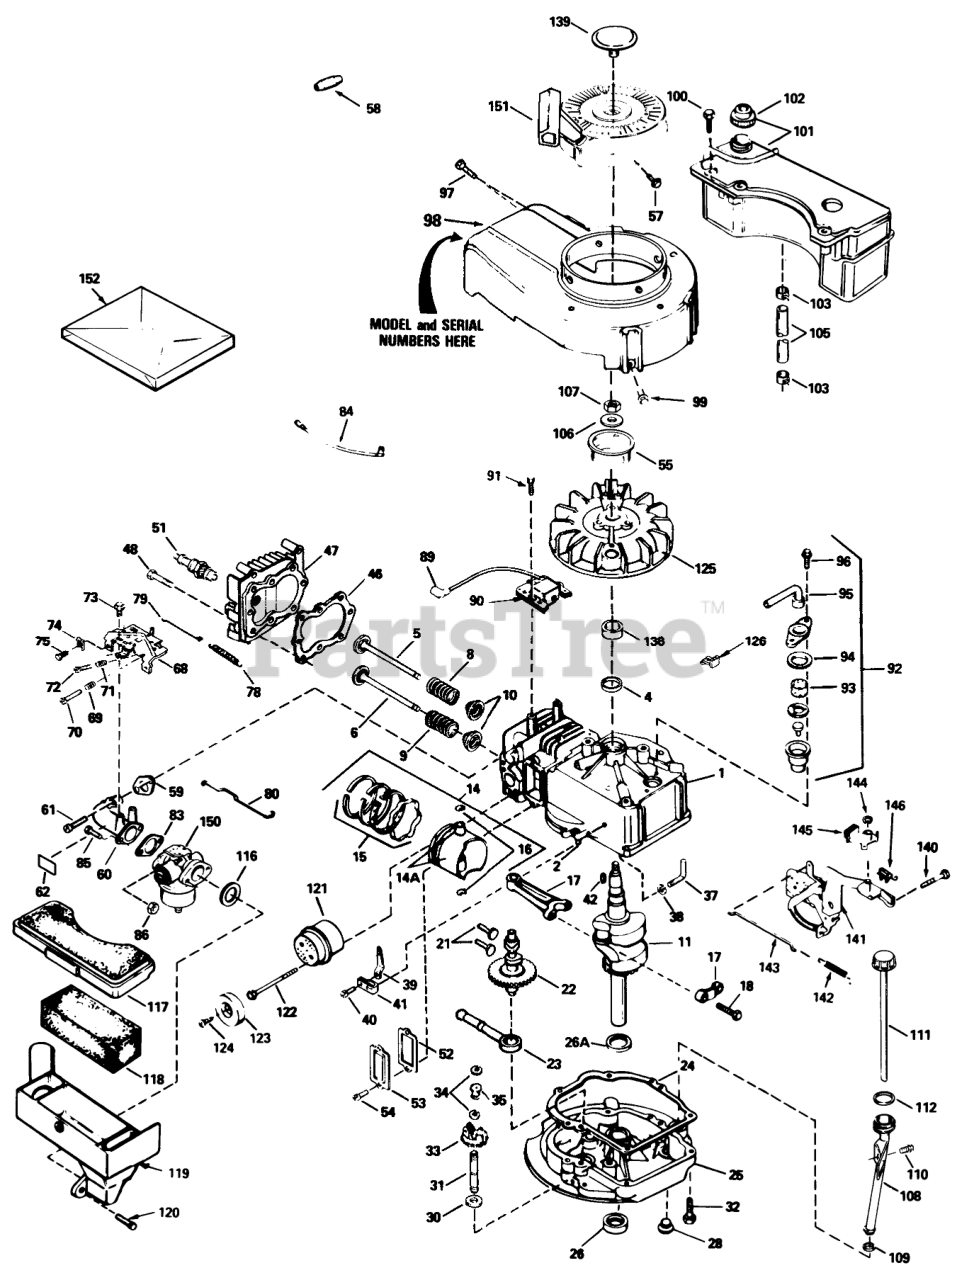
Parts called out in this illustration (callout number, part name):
1	Cylinder Assembly (Incl. Ref. #2 & 4)
2	Pin-Dowel
4	Seal-Oil
5	Valve-Intake (Std.) (Incl. Ref. #10)
5	Valve-Intake (1/32" oversize) (Incl. Ref. #10)
6	Valve-Exhaust (Std.) (Incl. Ref. #10)
6	Valve-Exhaust (1/32" oversize) (Incl. Ref. No.10)
8	Seal Assy., Intake
9	Spring-Valve
10	Cap-Valve, Spring
11	Crankshaft
14	Piston-Pin & Ring Assy. (Std.) (Incl. Ref. #14A, 15 & 16)
14	Piston-Pin & Ring Assembly (.010 oversize) (Incl. Ref. #14A, 15 & 16)
14	Piston-Pin & Ring Assembly (.020 oversize) (Incl. Ref. #14A, 15 & 16)
14A	Piston & Pin Assembly (Std.) (Incl. Ref. #16)
14A	Piston & Pin Assembly (.010 oversize) (Incl. Ref. #16)
14A	Piston & PiN Assembly (.020 oversize) (Incl. Ref. #16)
15	Ring Set-Piston (Std.)
15	Ring Set, Piston(.0100versize)
15	Ring Set (.020" OS)
16	Ring-Retaining, Piston Pin
17	Rod Assembly-Connecting (Incl. Ref. #18)
18	Bolt-Rod, Connecting
21	Lifter-Valve
22	Camshaft(Mech.Comp. Release)
23	Oil Pump ASM
24	Gasket
25	Flange Assembly-Mounting (Incl. Ref. #26, 28 & 31)
26	Seal-Oil
26A	Washer-Thrust
28	Plug Oil Drain
30	Washer-Flat
31	Shaft-Governor
32	Screw (1/4-20 x 1-1/4)
33	Gear Assembly-Governor (Incl. Ref. #30)
34	Ring-Retaining
35	Spool-Governor
37	Rod-Governor (Incl. Ref. #38)
38	Washer-Flat
39	Governor Lever
40	Screw
41	Clamp-Lever, Governor
42	Key-Flywheel
46	63573 GIL 42 SNWTHW
47	Head-Cylinder
48	Screw (5/16-18x1-1/2)
51	Spark Plug-Resistor (R J19 L M)
52	Gasket-Breather
53	Cover-Valve
55	Hub-Starter
57	Screw, Hex Hd.
58	Retainer-Starter Rope
59	Gasket-Intake
60	Pipe-Intake (Incl. Ref. #59)
61	Screw (1/4-20 x 1)
62	Decal-Primer
68	Control Assy.-Remote Speed (Incl. Ref. #69 thru 72)
69	61709/GIL1515A/95-5
70	Screw
71	Spring-Compression
72	Screw
73	Screw (10-24 x 9/16)
74	Conduit
75	Screw (10-32 x 3/8)
78	Spring Governor
79	2035A67 ADD.ASSEMBL
80	Link-Throttle
84	Ground Wire
85	Screw (1/4-28 x 7/8)
86	Nut and Lock Washer (1/4-28)
89	Cover-Spark Plug
90	Solid State
91	Screw
92	Breather Assembly (Incl. Ref. #93 thru 96)
93	Element-Breather
94	Gasket-Breather
95	Tube, Breaker
96	Screw (10-24 x 9/16)
97	Screw (10-24 x 9/16)
98	Housing-Blower
99	Screw (1/4-20 x 1/2)
100	Screw (10-32 x 35/64)
101	Tank Assembly-Fuel (Incl. Ref. #102)
102	Cap-Fuel
103	Clamp-Line, Fuel
105	Line-Fuel
106	Washer-Belleville
107	Nut-Flywheel
108	Oil Fill Tube
110	Screw (10-32 x 1/2)
111	Dipstick
116	Gasket-Cleaner, Air
117	Cover-Air Cleaner
118	Filter-Air Cleaner
119	Body Air cleaner
121	Muffler (Incl. Ref. #122)
123	Cover-Muffler
124	Screw (8-32 x 3/8)
125	Flywheel
126	Clip-Wire
139	Plug Starter
140	Screw (1/4-20 x 3/8)
141	Bracket-S.E. Brake
142	Spring-Extension
143	Link-Control
144	Ring-Retaining
145	Lever-Brake
146	Terminal
150	Carburetor (Inc. Ref. #83)
151	Starter-Rewind
152	Gasket Set (Incl. Items Marked )
